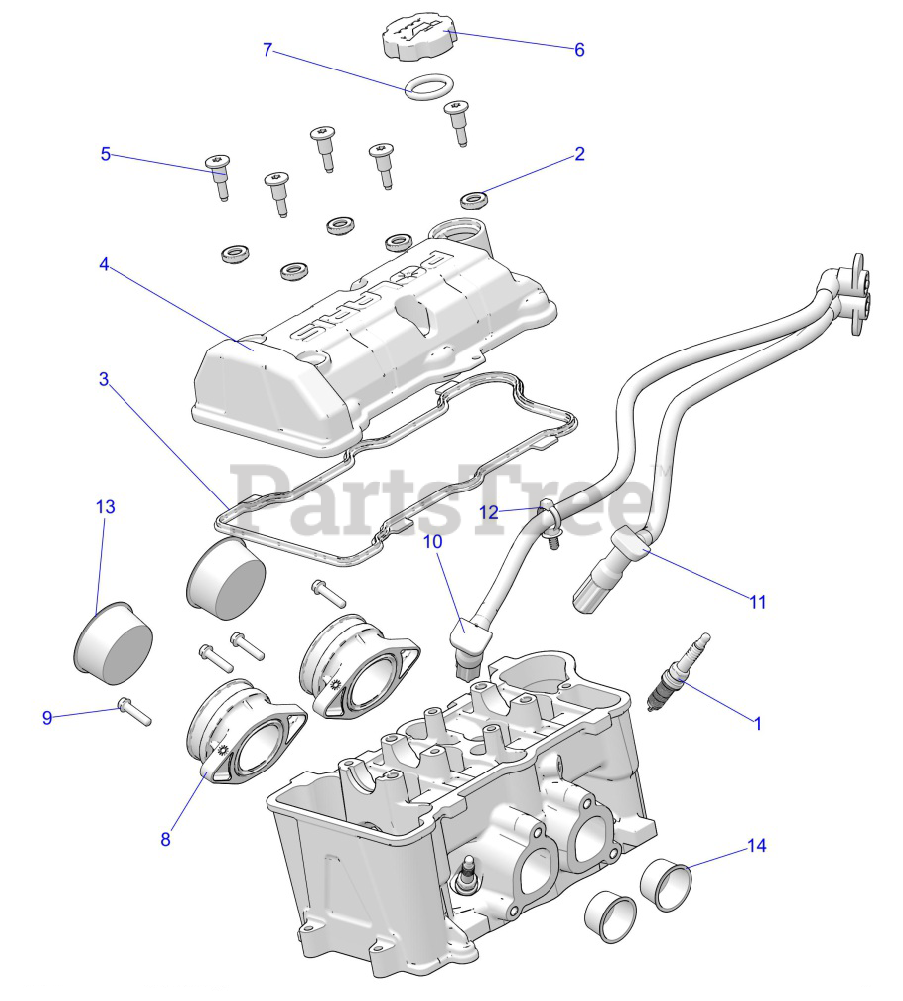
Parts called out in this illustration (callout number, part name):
1	SPARK PLUG- 12 MM
2	ISOLATOR-VALVE COVER
3	SEAL-VALVE COVER- 2 CYL- SOHC
4	COVER-VALVE-CAST-2 CYL- SOHC
5	BOLT-SHLDR-M6X12X15
6	ASM-OIL FILL CAP
7	O-RING-FILL CAP
8	ADAPTER-MANIFOLD
9	SCR-HXFLG-M6X1.0X25-10.9
10	WIRE-SPARKPLUG, MAG
11	WIRE-SPARKPLUG-PTO
12	CLIP-ROUTING
